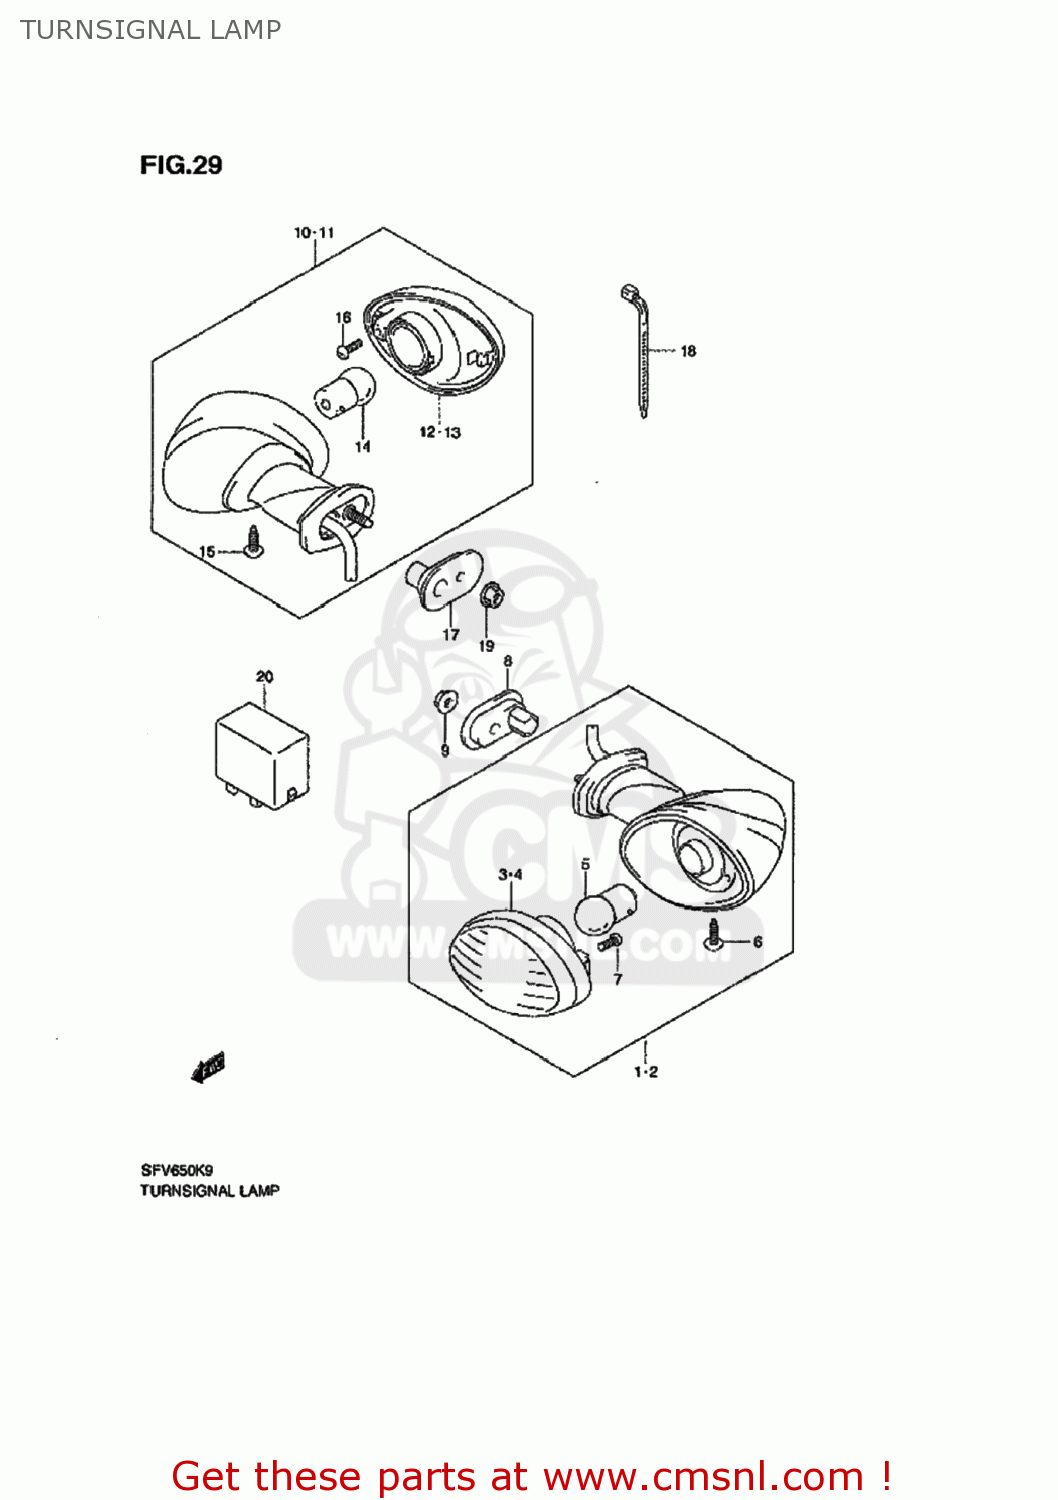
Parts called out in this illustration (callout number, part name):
1	LAMP ASSY,FR TURN SIGNAL,R
2	LAMP ASSY,FR TURN SIGNAL,L
3	LENS
4	LENS
5	BULB(12V21W,AMBER)
6	SCREW
7	PLATE,FR TURNSIGNAL
8	NUT
9	LAMP ASSY,RR TURNSIGNAL,R
10	LAMP ASSY,RR TURNSIGNAL,L
11	LENS
12	LENS
13	BULB(12V21W,AMBER)
14	SCREW
15	PLATE,FR TURNSIGNAL
16	CLAMP(L:165)
17	NUT
18	RELAY ASSY,TURNSIGNAL LAMP
